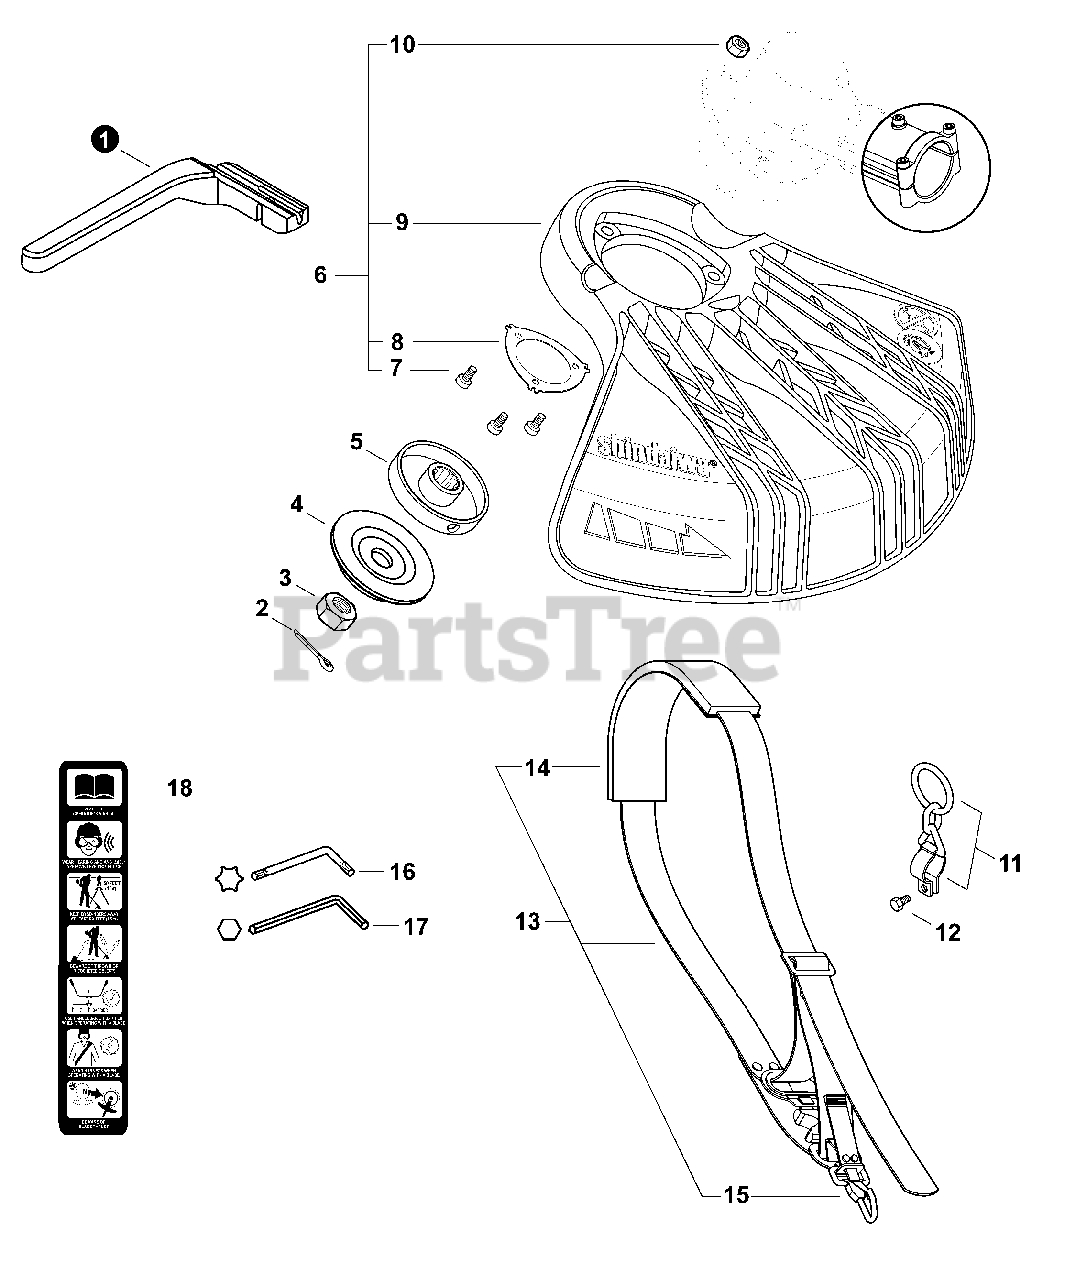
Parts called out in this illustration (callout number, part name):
1	BAR, BARRIER
2	PIN, COTTER 2x22
3	NUT 10x1.25 LH
4	PLATE, ADAPTOR - LOWER
5	PLATE, ADAPTOR - UPPER
6	DEBRIS SHIELD KIT - BLADE
7	BOLT, TORX 5x25
8	PLATE, SHIELD
9	SHIELD, DEBRIS - BLADE
10	NUT, LOCK M5
11	HANGER SET, HARNESS
12	BOLT, TORX 5x12
13	HARNESS ASSY, SHOULDER
14	PAD, SHOULDER
15	HOOK, SNAP
16	WRENCH, T27 80x30
17	WRENCH, ALLEN 4 MM
18	LABEL - CAUTION (BLADE CAPABLE)
